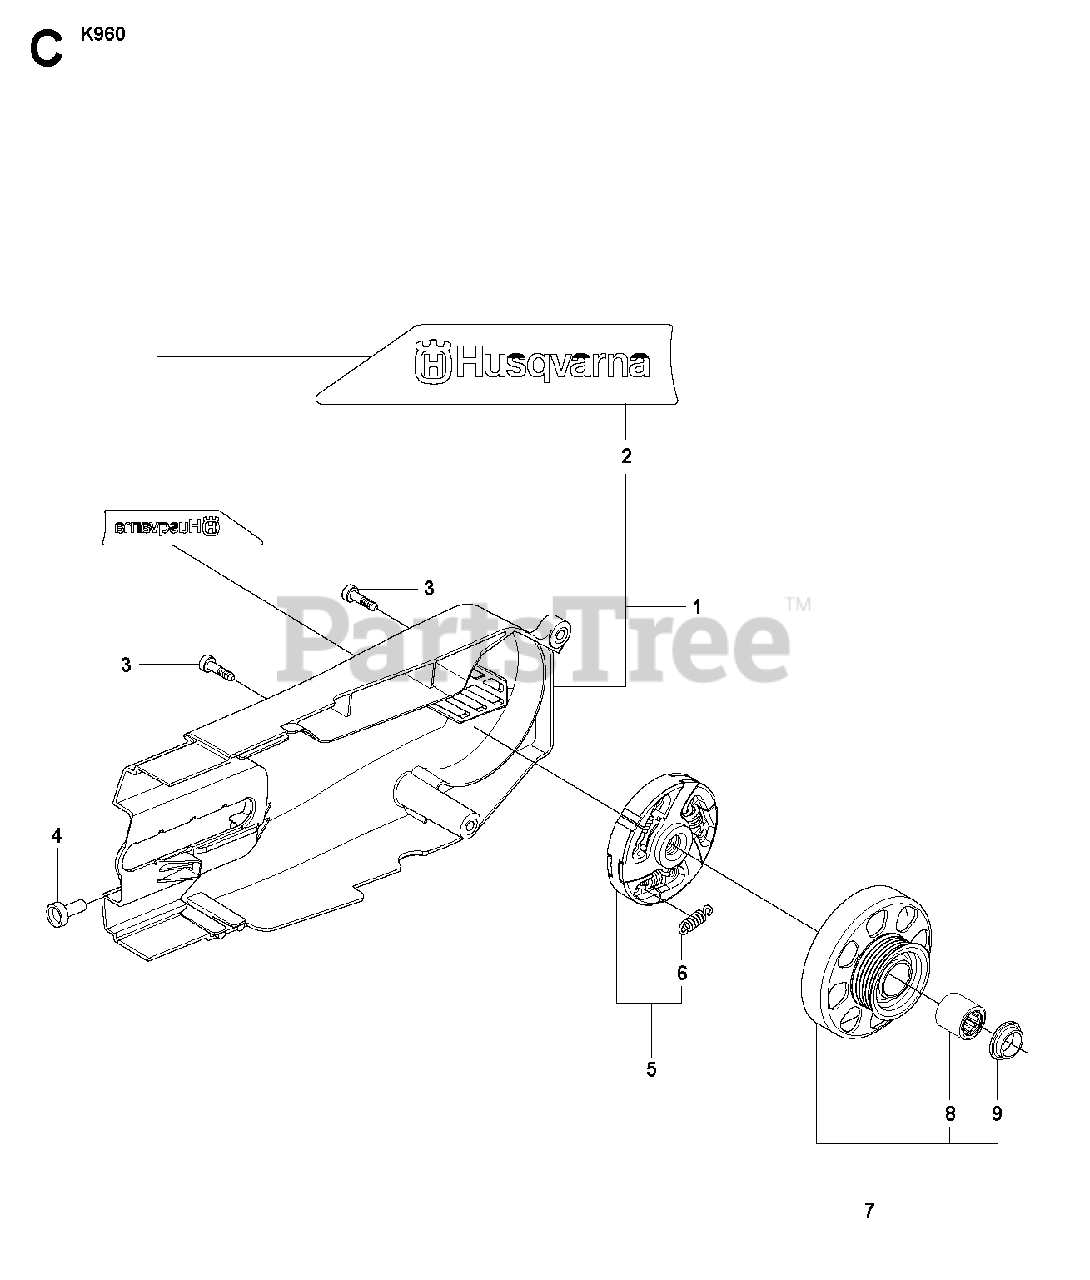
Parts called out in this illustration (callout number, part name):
1	BELT GUARD ASSYIncl. 2
3	SCREW ITXSCM
5	CLUTCH ASSYIncl. 6
6	CLUTCH SPRING
7	DRIVING PULLEY ASSY"12"", 14"". Incl. 8, 9"
7	DRIVING PULLEY ASSY"16"". Incl. 8, 9"
8	NEEDLE BEARING
